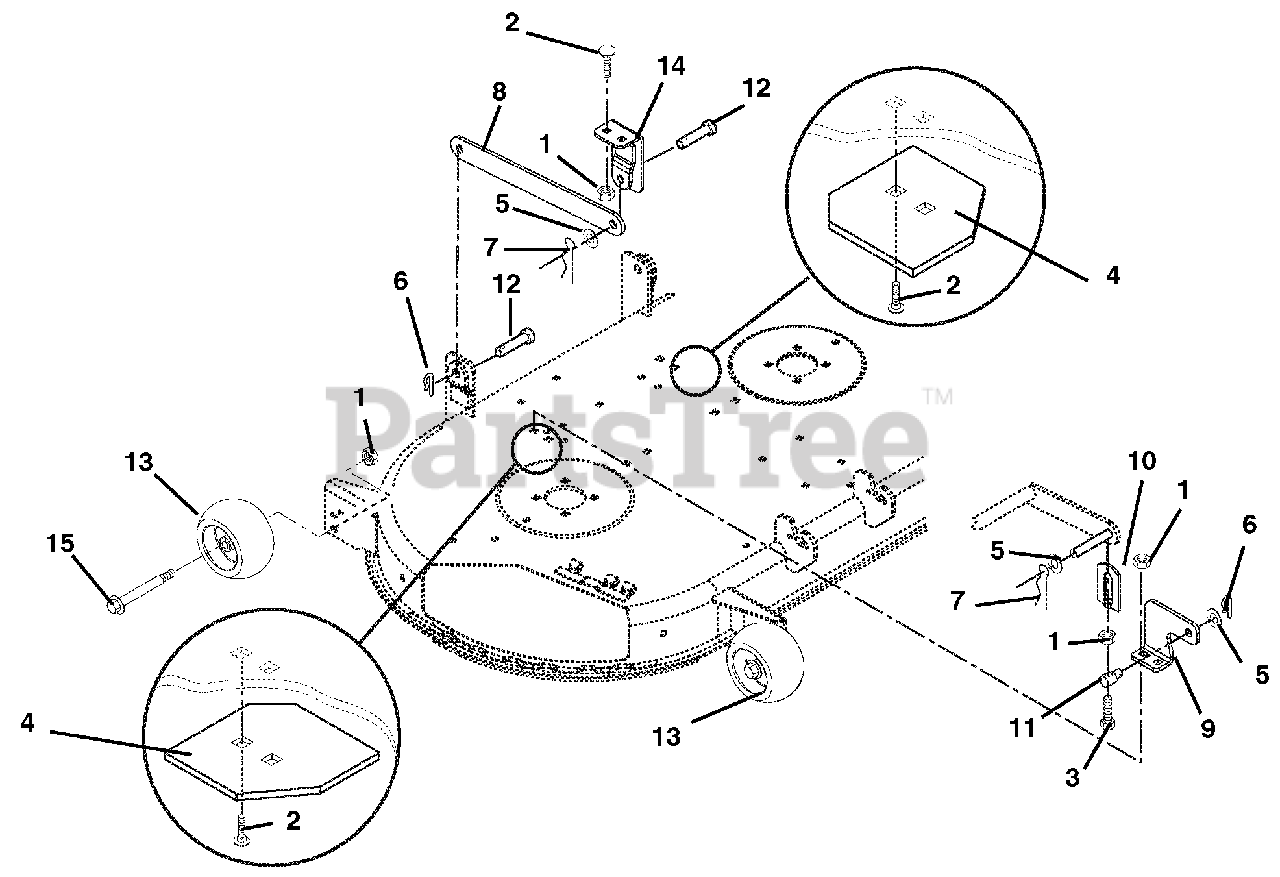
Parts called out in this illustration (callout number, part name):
1	Nut-Locking-Top-Flange .38-16
2	Bolt Round Head Square Neck .38-16
3	Bolt-Hex .38-16 x 2.50 Grade 5
4	Reforcement, Deck Lift
5	Washer-Flat-Steel .505 x .88 x .072
6	Clip-Spring
7	Pin-Hair-External .12 x .31 x 2.37
8	Link-Lift
9	Bracket-Lift
10	Link-Adjustment
11	Trunnion
12	Pin-Clevis .50 x 1.00
13	Wheel 5" x 3"
14	Weldment-Deck Stop Bracket
15	Bolt-Shoulder .38-16 x 2.50 Hex Washer Head Grade 5
